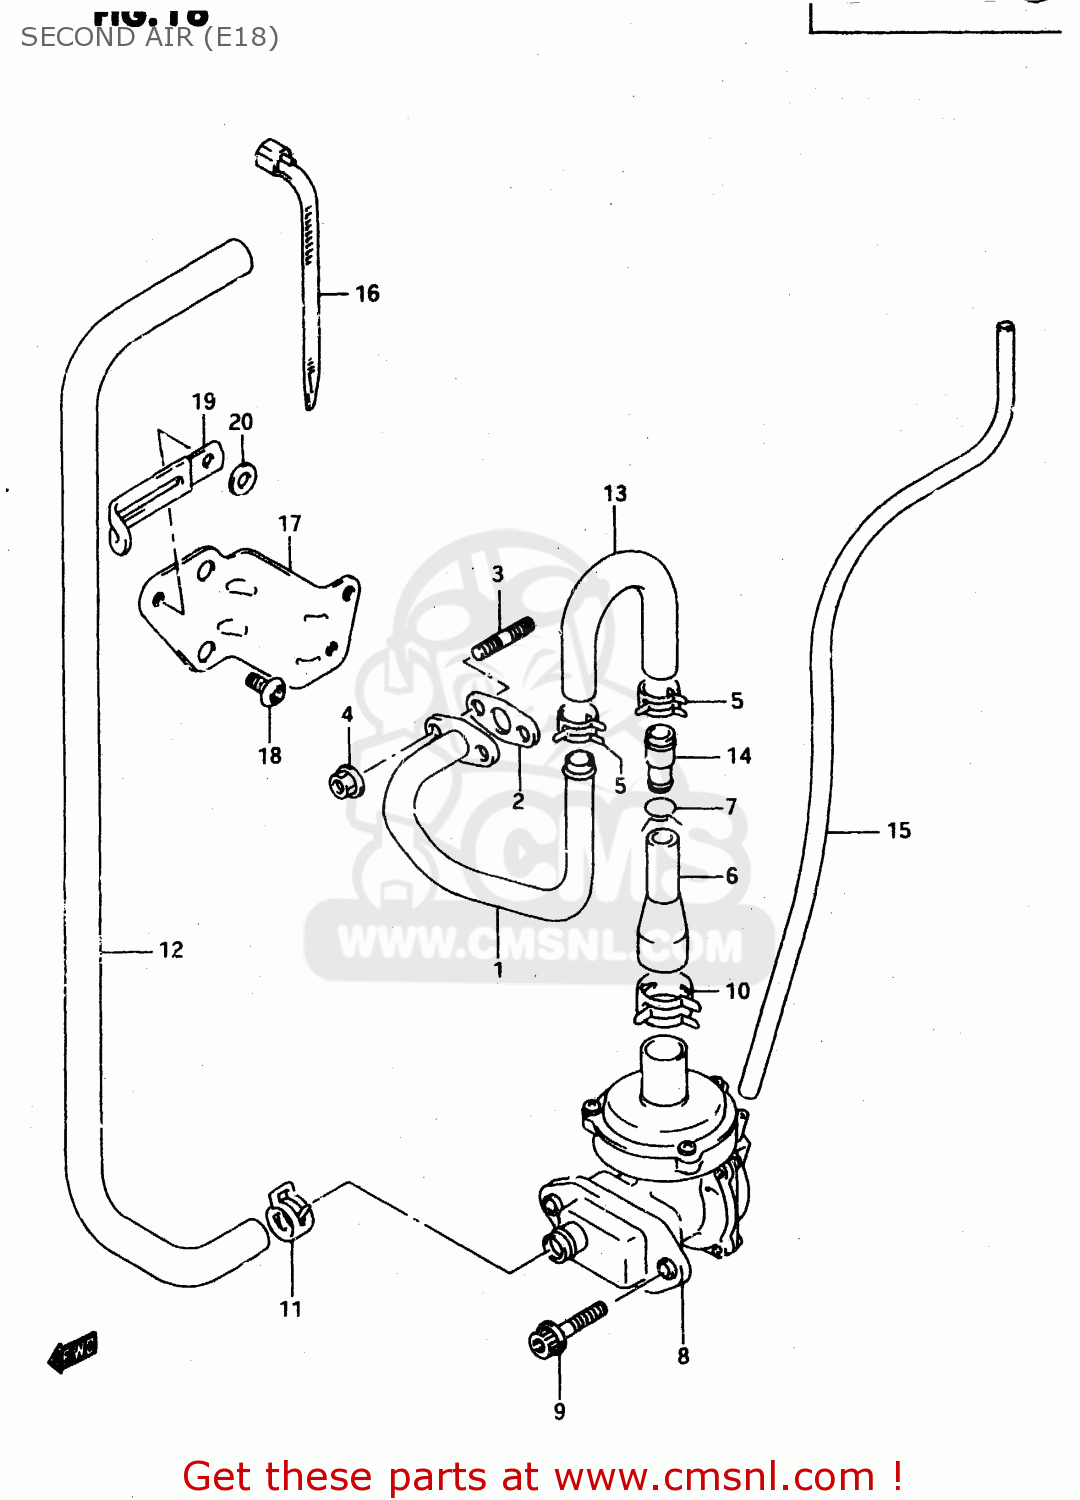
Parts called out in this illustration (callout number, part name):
1	PIPE, 2ND AIR
2	GASKET,SECOND AIR PIPE (N (NAS)
3	STUD BOLT
4	NUT
5	CLIP
6	HOSE, 2ND AIR
7	CLIP
8	VALVE ASSY, 2ND AIR REED
9	BOLT MAGNETO S
10	CLIP
11	CLIP
12	HOSE, 2ND AIR NO.4
13	HOSE,SECOND AIR REED VALVE
14	UNION, 2ND AIR HOSE
15	HOSE(4X7X600)
16	CLAMP
17	BRACKET,OIL COOLER UPR
18	BOLT(8X12)
19	CLAMP
20	WASHER
